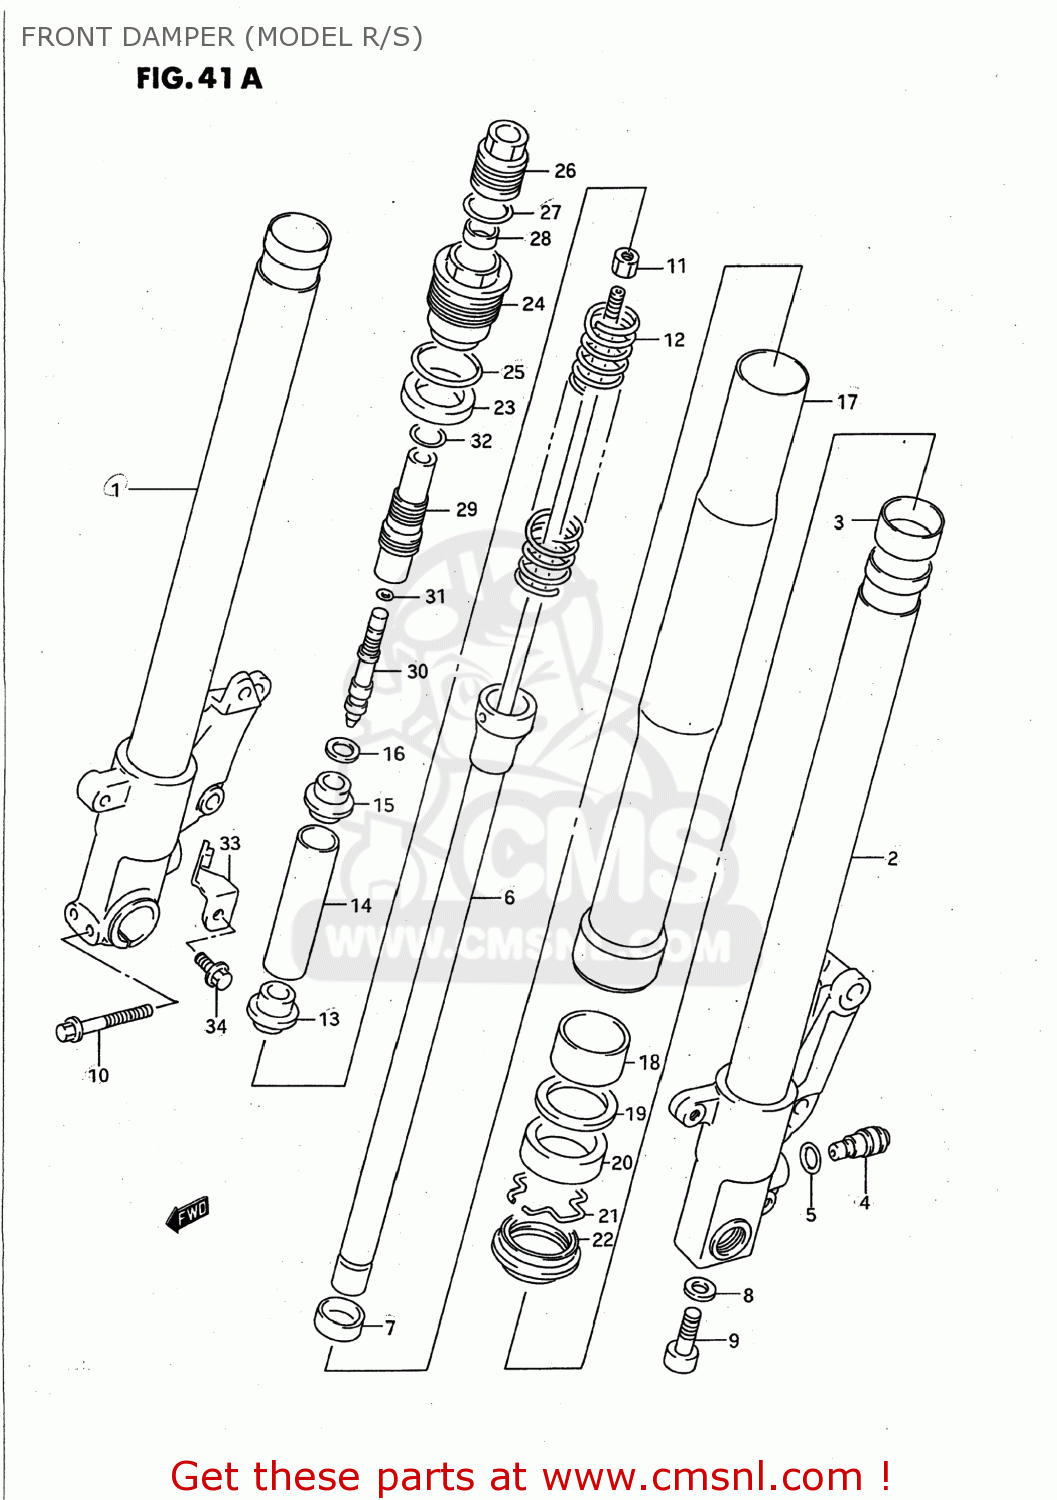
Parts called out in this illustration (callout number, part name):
1	TUBE,INNER,R
2	TUBE,INNER,L
3	BUSH,SLIDE
4	PIECE,ADJUSTER
5	O RING
6	DAMPER,FRONT
7	PLATE,CENTERING
8	WASHER(10X15X1.5)
9	BOLT
10	BOLT
11	NUT
12	SPRING,MAIN
13	JOINT,SPRING
14	SPACER,SPRING
15	GUIDE,SPRING UPR
16	GUIDE,SPRING
17	TUBE,OUTER
18	BUSH,GUIDE
19	SPACER,SEAL
20	SEAL,OIL
21	CIRCLIP,FORK OIL SEAL
22	SEAL,DUST
23	RUBBER,SEAT
24	BOLT,FORK
25	O RING,FORK BOLT
26	ADJUSTER,SPRING
27	O RING
28	PLATE,SPRING ADJUSTER
29	CASE,ADJUSTER
30	PIECE,ADJUSTER
31	O RING
32	RING,STOPPER
33	PLATE,FRONT FENDER,LEFT
34	BOLT
